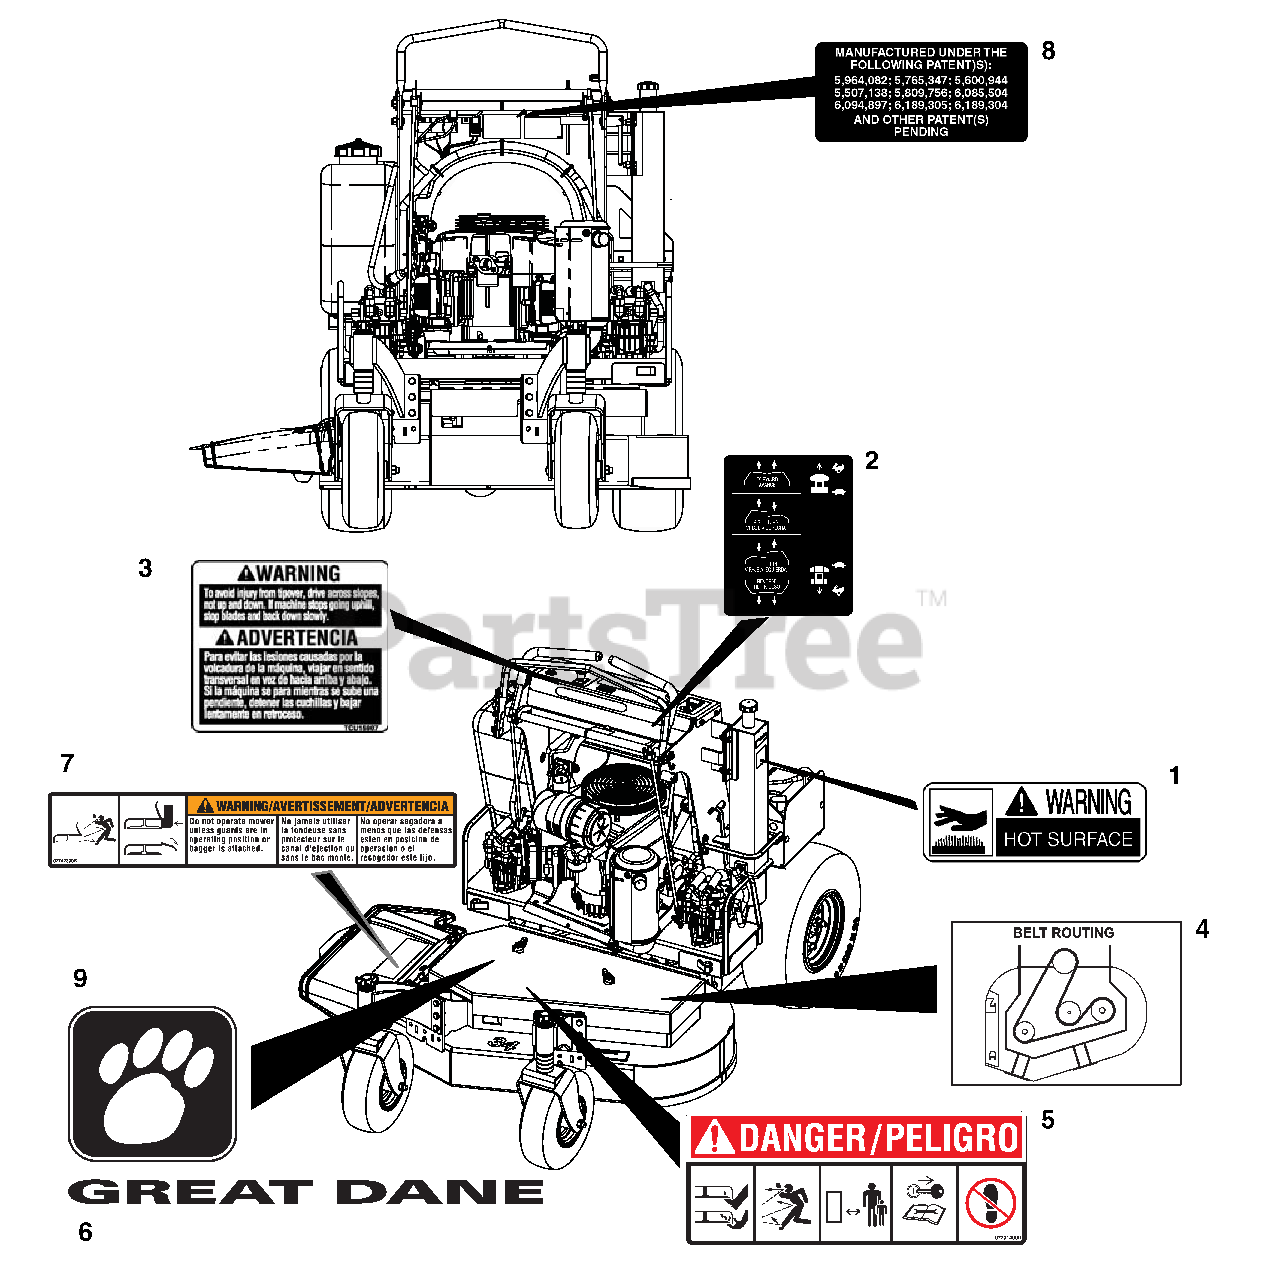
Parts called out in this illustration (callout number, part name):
1	LABEL, WARNING (HOT SURFACES)
2	DECAL, DIRECTIONAL CONTROL
3	DECAL, WARNING - SLOPE
4	DECAL, BELT ROUTING 34
5	DECAL, MOWER PAN DANGER
6	DECAL, GREAT DANE
7	DECAL, WARNING
8	DECAL, PATENT
9	DECAL, PAW PRINT
